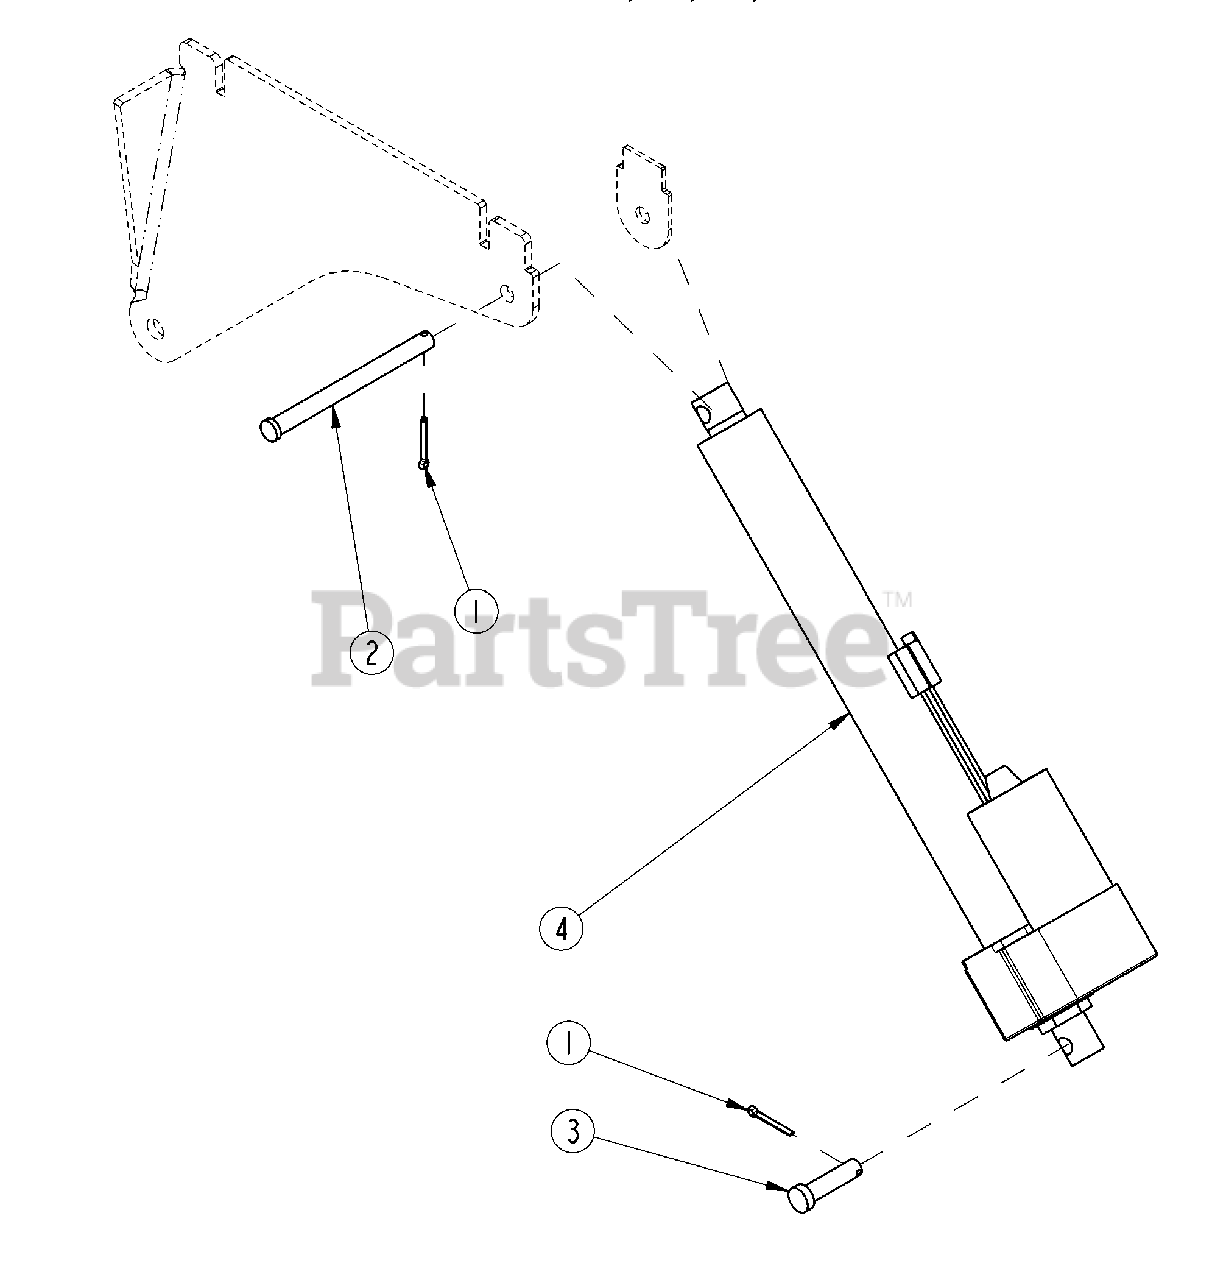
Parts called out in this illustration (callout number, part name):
1	RING, RUE .500 X .062 X 1.420
2	PIN, CLEVIS 1/2 X 5.76
3	PIN, CLEVIS .50 X 2.00 X 1.71 YWZC
4	ELECT. LINEAR ACTUATOR 12" STRK
